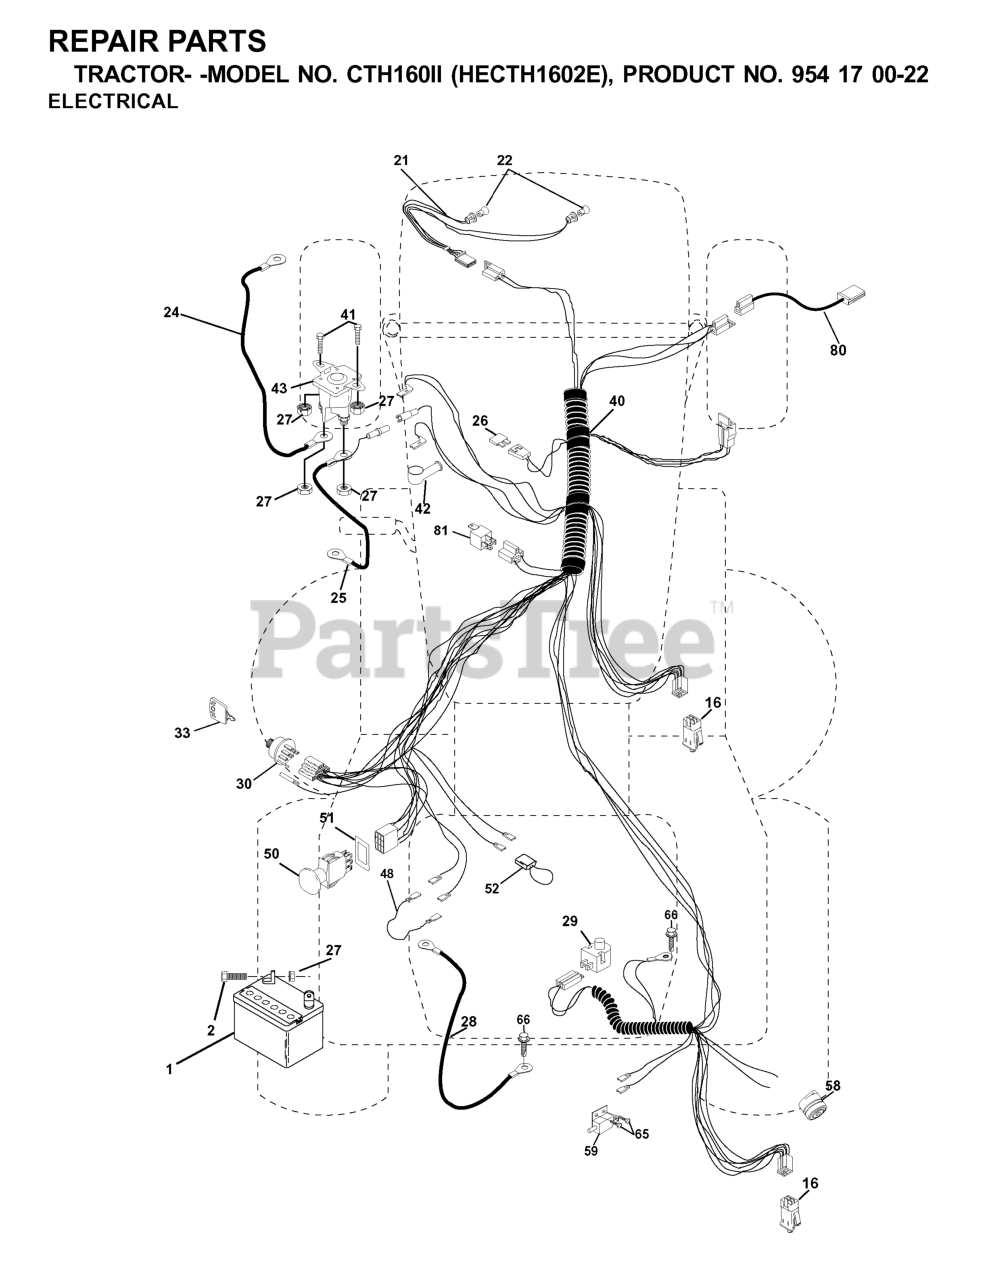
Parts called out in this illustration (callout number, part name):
1	BATTERY 12V .35 AMP
2	BOLT.HEX.1/4.X.3/4.DICHROMATE
16	SWITCH INTERLOCK
24	BATTERY CABLE GT
25	CABLE BATTERY
26	FUSE 20AMP
27	NUT
28	CABLE GROUND
29	PLUNGER SWITCH (COLOR:OLIVE)
30	IGNITION SWITCH
33	KEY MLD GEN DELTA
40	HARNESS.ING.CRD.ELECT
41	BOLT
42	TERMINAL COVER
43	REPL BY 532 1461-54
48	ADAPTER.AMMETER
50	RP.PTO.SWITCH.8 TERMINAL.BLACK
51	FRAME RETAINING RING
52	WIRE PROTECTION LOOP
58	BUZZER
65	Screw, Hex Wsh. Tap #10-16 x 1/2
80	HARNESS, CLUTCH
81	RELAY.ASSY.T
